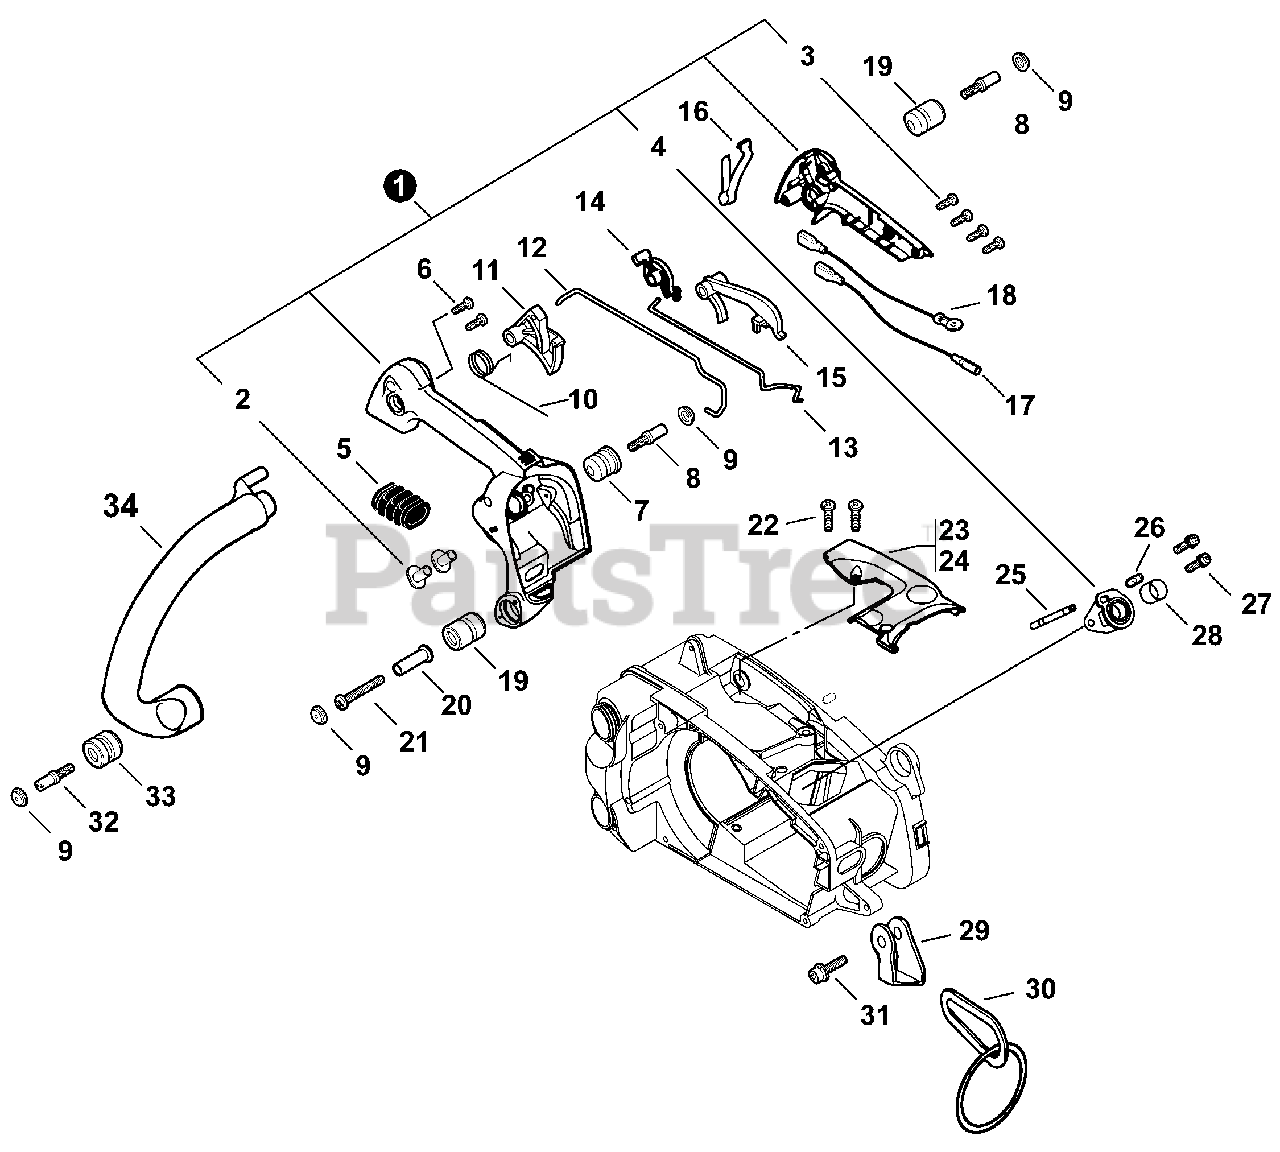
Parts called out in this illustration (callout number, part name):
1	HANDLE KIT, REAR
3	SCREW 4×16
4	BELLOWS, INTAKE
5	BELLOWS, INTAKE
6	SCREW 5×20
7	CUSHION 4
8	BOLT 4×15
9	CAP, CUSHION
10	SPRING, TORSION
11	TRIGGER, THROTTLE
12	ROD, THROTTLE
13	ROD, CHOKE
14	LEVER, CONTROL
15	LOCKOUT, THROTTLE
16	TERMINAL, LEAD
17	LEAD - GROUND
18	LEAD - IGNITION
19	CUSHION
20	COLLAR 4
21	SCREW, TAPPING 4×35
22	SCREW 4×12
23	COVER, DUST - GRAY
24	COVER, DUST - ORANGE
25	PIPE, PULSE 3×7×65
26	COLLAR 3.2×6.5
27	SCREW 5×12
28	COLLAR 16
29	BRACKET, HARNESS
30	RING, HARNESS
31	BOLT 4×25
33	CUSHION 5
34	HANDLE, FRONT
